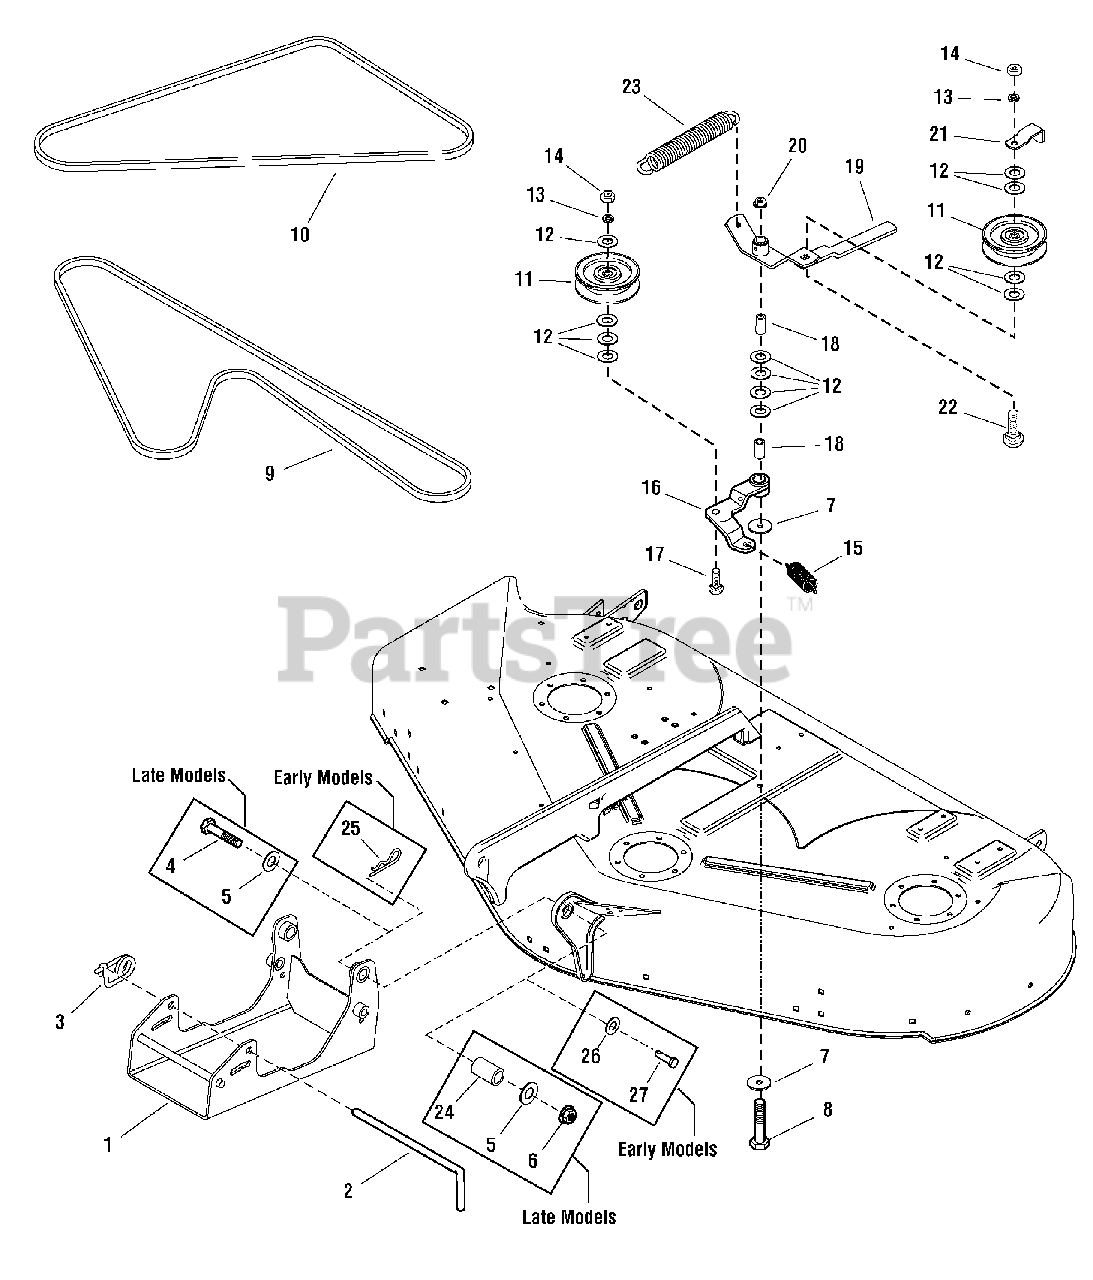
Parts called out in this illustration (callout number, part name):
1	HITCH & RODS ASSEMBLY, 4WD
3	SPRING PIN
4	CAPSCREW, 3/8-16 x 2
5	WASHER, 3/8
6	NUT, Hex Flange 3/8-16
7	WASHER, 3/8
8	CAPSCREW, Hex Head 3/8-15 x 3-1/2 G5
9	V-BELT, Arbor Drive
10	V-BELT, Mower Drive 70.1
10	V-BELT, Mower Drive 62.1
11	PULLEY, Idler
12	WASHER, 3/8
13	LOCKWASHER, Spring 3/8
14	NUT, Hex 3/8-16
15	SPRING, Extension
16	LEVER ASSEMBLY, Idler w/Bushing & Fitting
17	BOLT, Carriage, 3/8-16 x 1-1/2, G5
19	LEVER ASSEMBLY, Idler w/Bushings & Fitting
20	NUT, Hex Flange 3/8-16 Machine Lock
21	GUARD, Belt
22	BOLT, Carriage, 3/8-16 x 2, G5
23	SPRING, Extension
24	SPACER
25	HAIRPIN
26	WASHER, Flat, 3/4
27	PIN, Clevis
